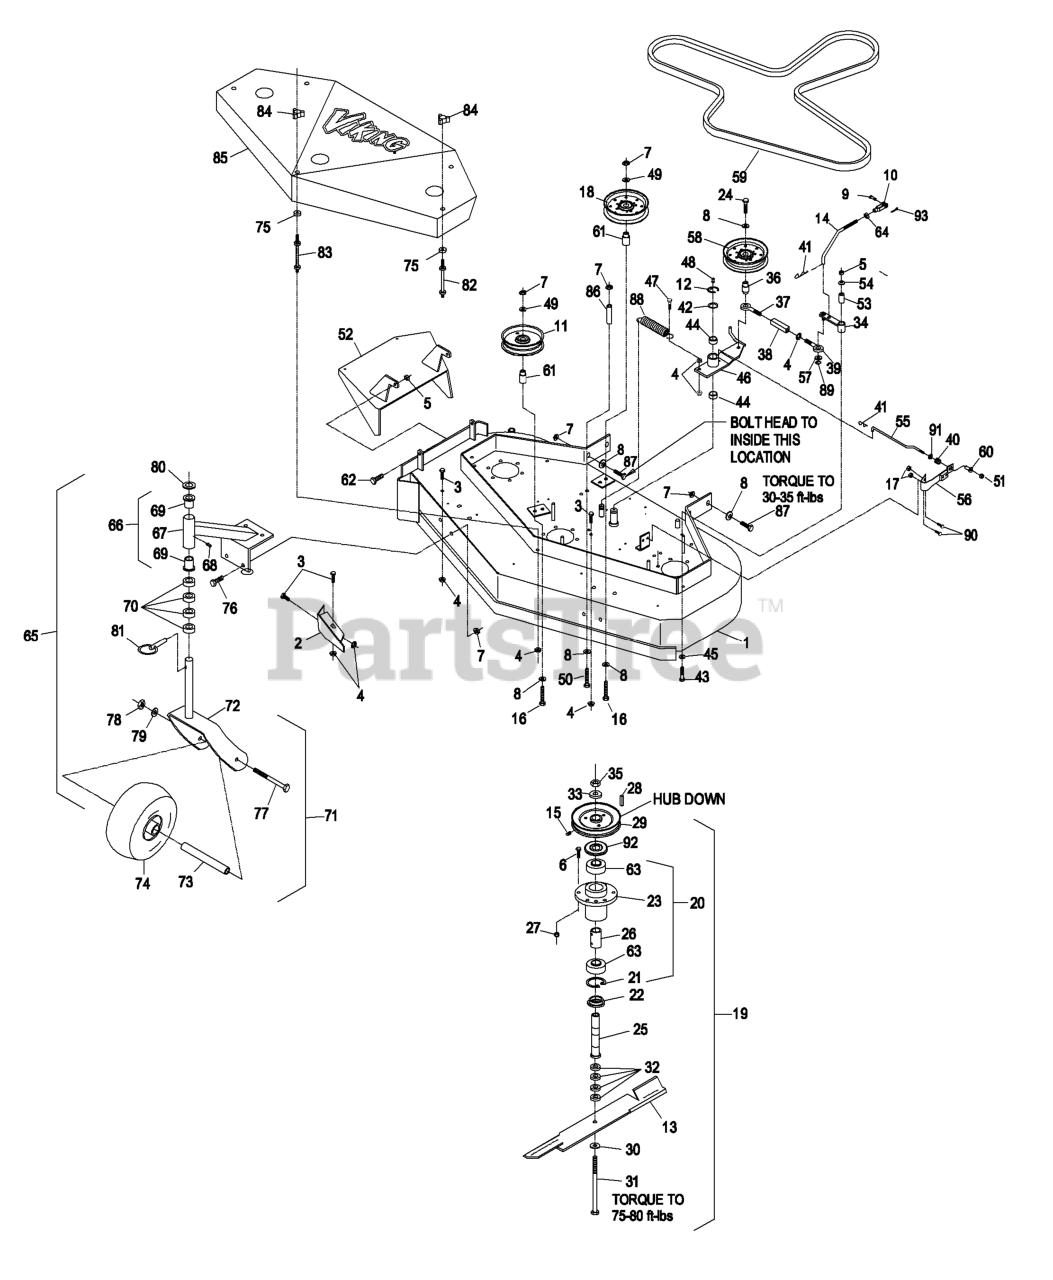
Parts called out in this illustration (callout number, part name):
1	DECK-SERVICE, 48
2	BAFFLE-DOGLEG
3	SCREW-HH
5	NUT-LOCK, NI
6	SCREW-HH
7	NUT-HHF, WHIZ
8	WASHER-BELLEVILLE
9	PIN-CLEVIS
10	YOKE-ADJUSTABLE
11	PULLEY-IDLER
12	RING-RETAINING, EXT
14	ARM-LINKAGE, ASSIST
15	SCREW-SET
16	SCREW-HH
17	NUT-LOCK, NI
21	RING-SNAP
22	SPACER-GUARD, BOTTOM
24	SCREW-HH
25	TUBE-SPINDLE, SHORT
26	SPACER-BEARING
27	NUT-LOCK, NI
29	SHEAVE
30	WASHER-SPRING
31	SCREW-CAP, HH
33	WASHER-RETAINER, SHEAVE
34	ARM-ASSIST
35	NUT-HEX
36	BUSHING-ENGAGEMENT
37	EYEBOLT-THREAD, LH
38	BODY-TURNBUCKLE
39	EYEBOLT-THREAD, RH
40	SPRING-COMPRESSION
41	PIN-COTTER
42	WASHER-SPINDLE
43	SCREW-HH
44	SLEEVE-BEARING
45	WASHER-SPRING
46	ENGAGE ARM ASM
47	SCREW-HH
48	FITTING-GREASE
49	WASHER-FLAT
50	SCREW-HH
51	NUT-LOCK, NI
52	WLD,CHUTE 48
53	TUBE-PIVOT
54	WASHER-FLAT
55	ROD-BRAKE
56	PAD AND SPRING ASM
57	WASHER-PLAIN
59	BELT,BLADE 48
60	SPACER-FLANGED
62	SCREW-HH
63	BEARING-JACKSHAFT
64	NUT-HEX
66	ASM,CSTR SUPPORT W/WEIGHT
68	FITTING-GREASE
69	BEARING-FLANGED
70	SPACER-CASTER
71	ASM,CASTER/WHEEL
73	SPACER FRONT CASTER
76	SCREW-HH
77	SCREW-HH
78	NUT-HH
79	WASHER-LOCK
80	WASHER-FLAT
82	STUD-SHIELD, BELT (SHORT)
83	STUD-SHIELD, BELT (LONG)
84	KNOB-3 PRONG
87	SCREW-HH
88	SPRING-EXTENSION
89	RING-RETAINING, EXT
90	SCREW-HH
91	RING-PUSH ON
92	GUARD-BEARING, TOP
93	PIN-COTTER
94	KIT, SP CASTER WHEEL REPL
